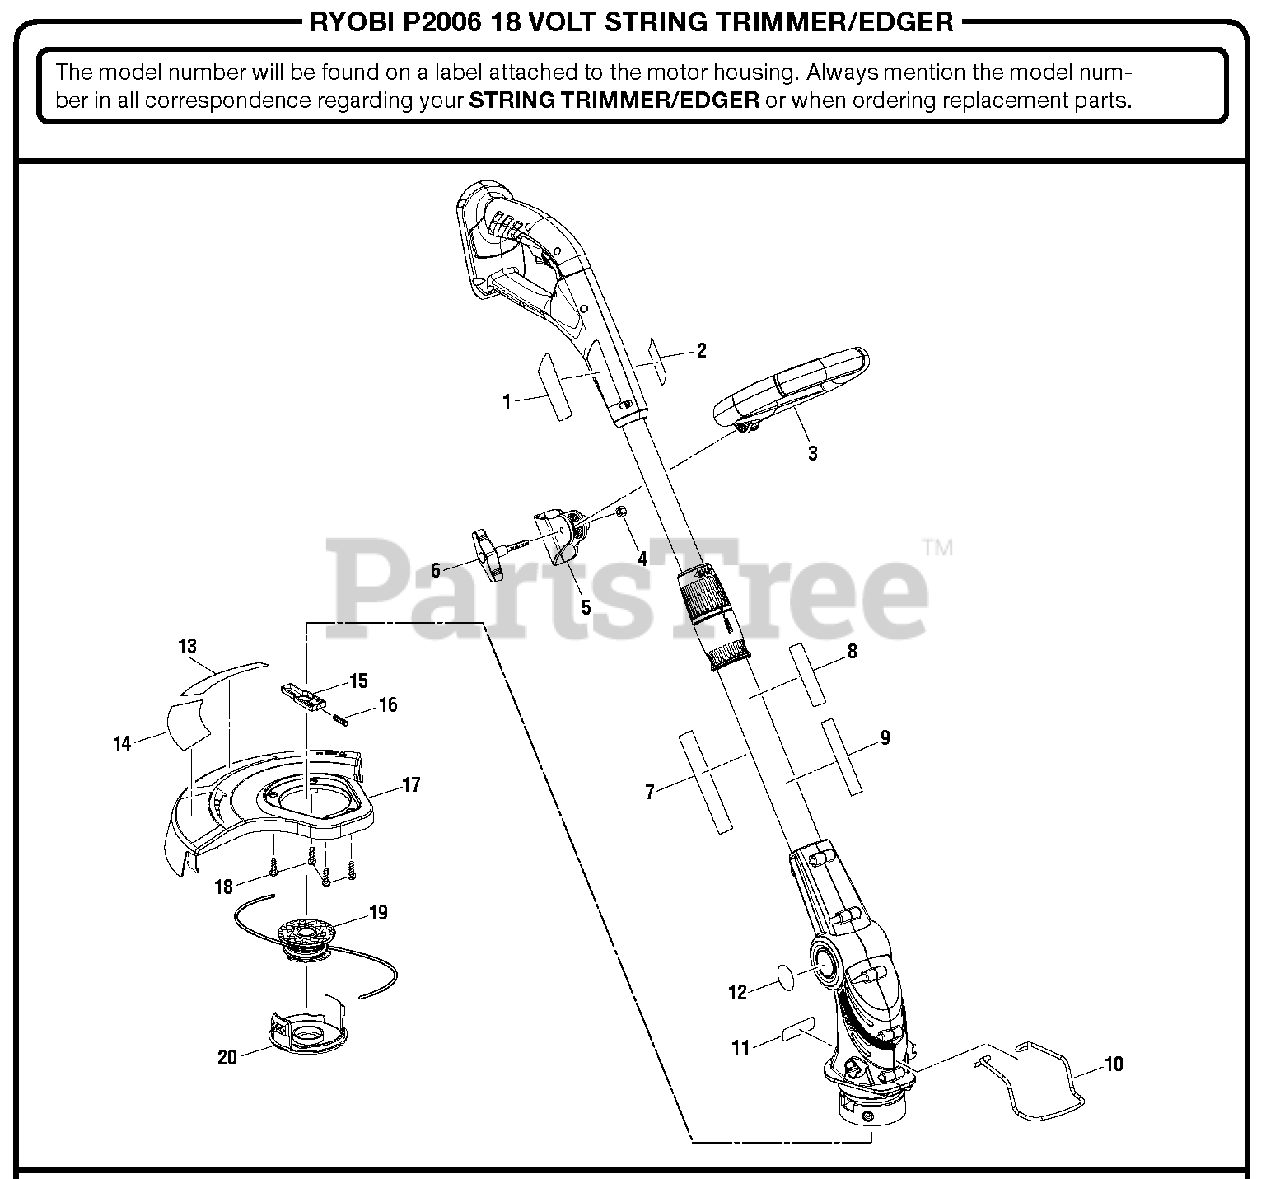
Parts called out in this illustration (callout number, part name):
1	Data Label
2	Logo Label (Handle)
3	Front Handle
4	Hex Nut (M6)
6	Knob Screw (M6)
7	Warning Label (Fr/Sp)
8	Warning Label (Icon)
9	18V Lithium-Ion Label
10	Edger Guide
11	Logo Label (Housing)
12	Pivoting Head Label
13	Auto Line Feed Label
14	Adjustable Cutting Width Label
15	Slider Assembly
16	Compression Spring
17	Grass Deflector Assembly
18	Screw (M4 x 12 mm)
19	Spool w/Line (AC14RSLA)
20	Spool Cap (AC14HCA)
